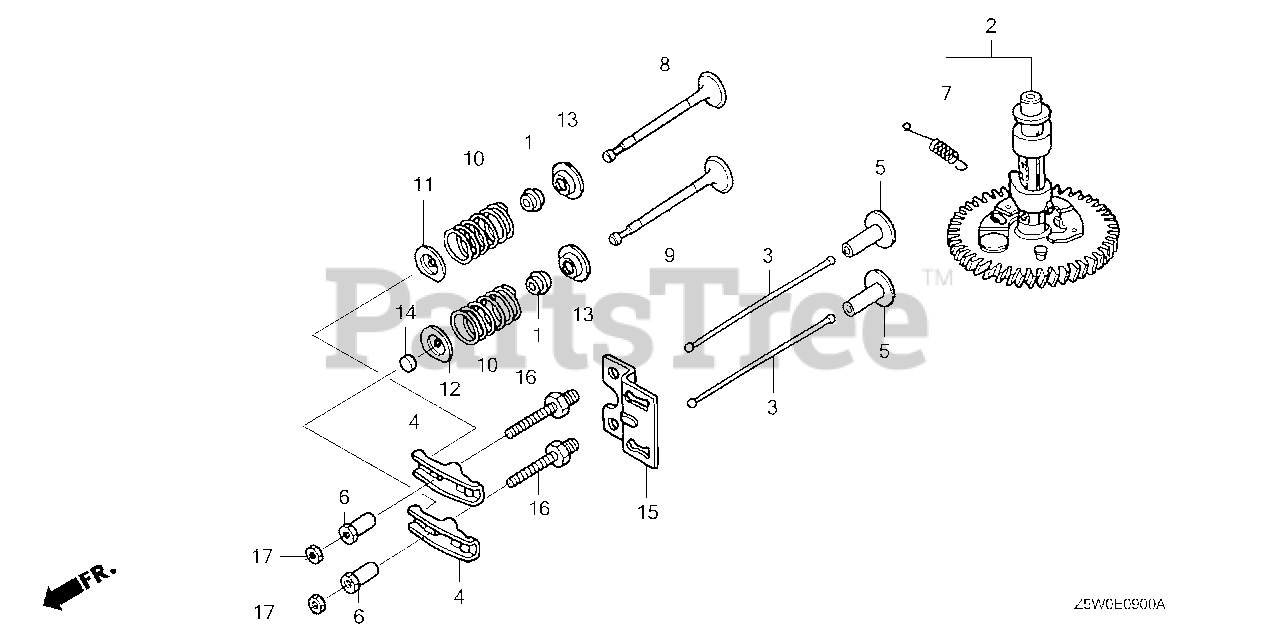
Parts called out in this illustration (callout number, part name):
1	SEAL, VALVE STEM
2	CAMSHAFT ASSY.
4	ARM, VALVE ROCKER
5	LIFTER, VALVE
6	PIVOT, ROCKER ARM
7	SPRING, WEIGHT RETURN
8	VALVE, IN.
9	VALVE, EX.
10	SPRING, VALVE
11	RETAINER, IN. VALVE SPRING
12	RETAINER, EX. VALVE SPRING
13	SEAT, VALVE SPRING
14	ROTATOR, VALVE
15	GUIDE, PUSH ROD
16	BOLT, PIVOT (8MM)
17	NUT, PIVOT ADJUSTING
